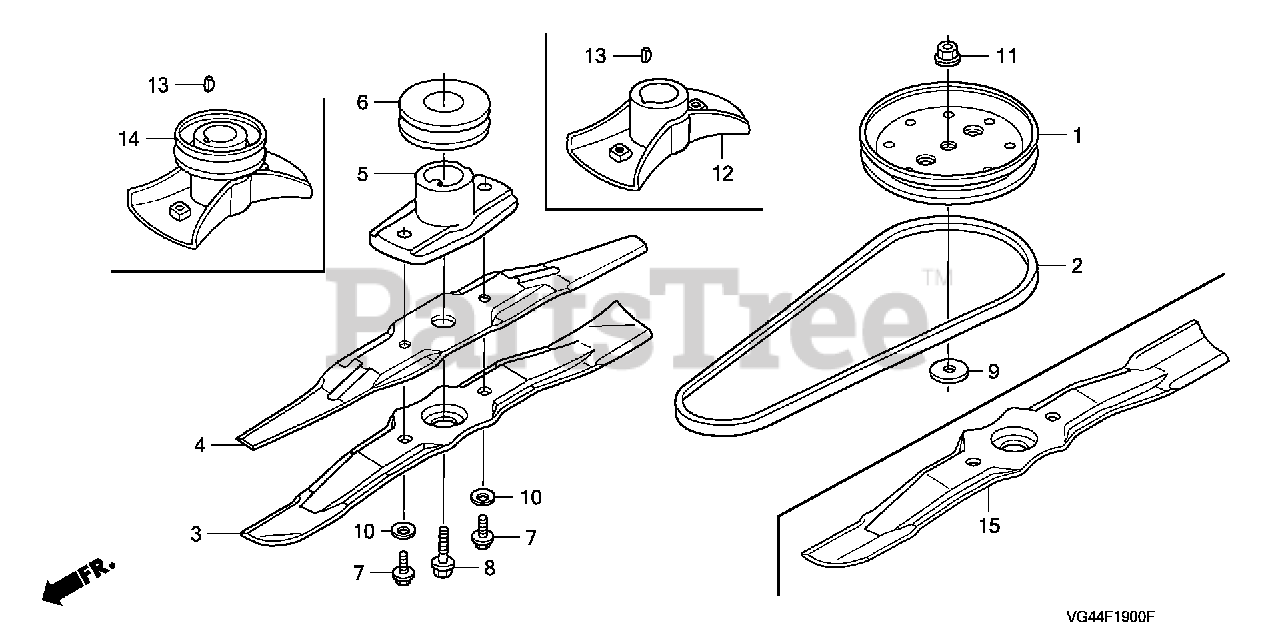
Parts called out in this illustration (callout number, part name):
3	BLADE, ROTARY (PCD=88MM)
4	BLADE, ROTARY (UPPER) (PCD=88MM)
7	BOLT, HEX. (10X20)
8	BOLT, FLANGE (3/8-24X1")
10	WASHER, SPRING (10MM)
12	KIT, BLADE HOLDER
12	HOLDER KIT, BLADE
13	KEY, WOODRUFF (3/16X5/8)
